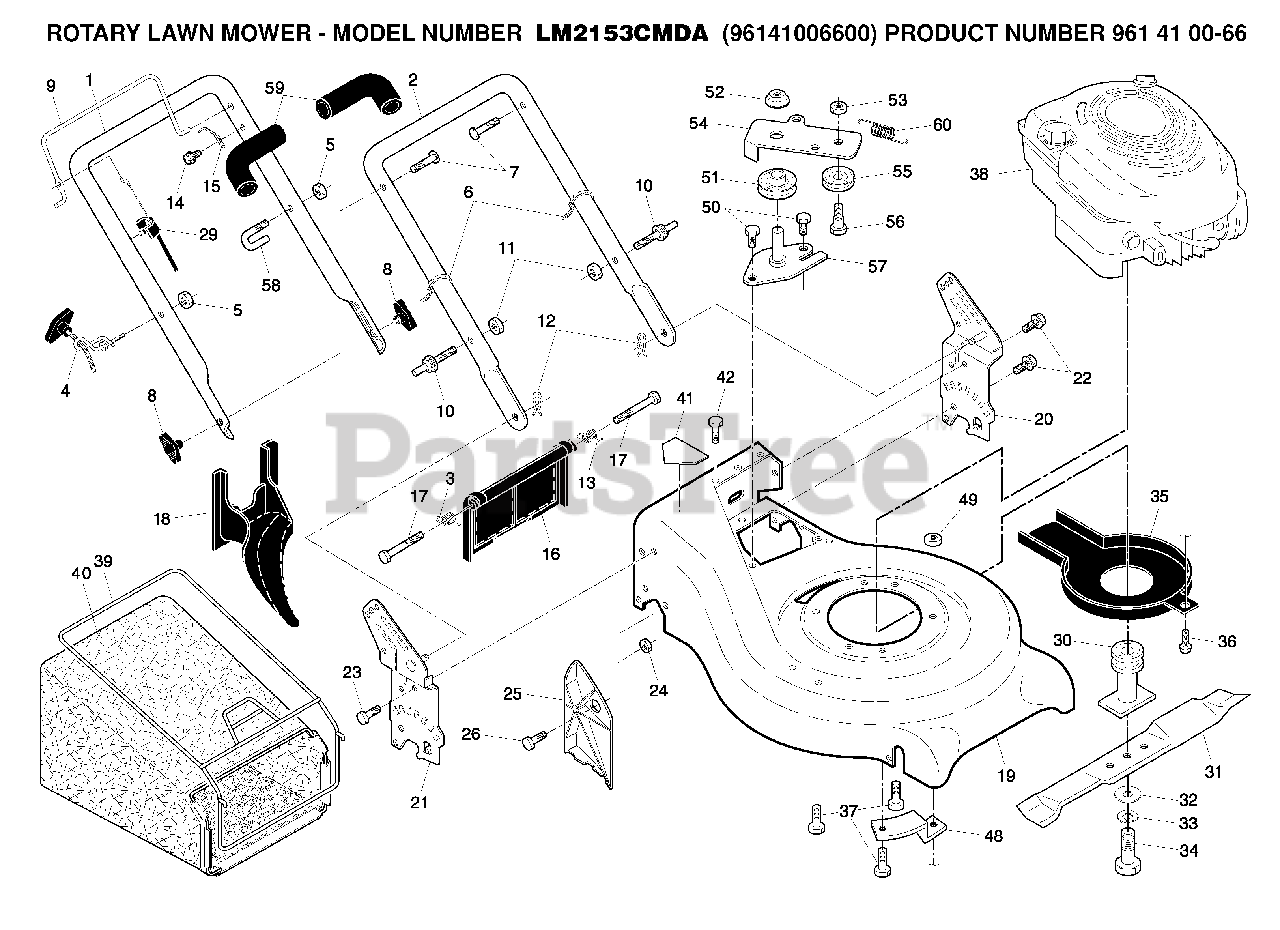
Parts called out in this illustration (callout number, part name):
2	HANDLE LOWER
3	SPRING, REAR DOOR, RH
4	GUIDE.ROPE.STD.BLK.ZIN
5	NUT
6	TIE GUIDE
7	BOLT, HANDLE 5/16-18X1.75
8	KNOB, DEFLECTOR
11	NUT.CENTERLOCK.5/16-
12	HAIRPIN COTTER
13	SPRING.LH.REAR.DOOR.21.RWGD
15	BRACKET UPSTOP
16	DOOR.REAR.PLASTIC.21.RWGD.BLAC
18	PLUG.MULCHER.RGD.21.
20	BRKT.ASM HNDL
21	BRKT.ASM.HNDL
22	SELF-TAPPING SCREW 5/16-18X3/4
23	BOLT, HEX HEAD 5/16-18
24	NUT.71038.31-18.HEX.NYLOCK
25	CLIPPING DEFLECTOR
29	SNAP-ON.ZONE.CABLE.ASS
30	BLADE ADAPTOR / PULLEY
31	BLADE.21.PUSH
32	WASHER,HARDEN
33	LOCKWASHER
34	SCREW, HEX HD 3/8-24 X 1-3/8
35	DEBRIS SHEILD
36	SCREW.HEX.WSH
37	BOLT 3/8-16X1-1/8
40	FRAME.CATCHER.21.RGD.AG
41	DECAL.INTERNATIONL.CUTFINGER
48	BRACKET
51	PULLEY.IDLER
52	NUT
54	ARM.IDLER
55	IDLER PULLEY
57	BRACKET.IDLER.ASM.EZ
59	GRIP.HANDLE.FOAM.WIDE.(1 SIDE)
60	SPRING, RETURN
